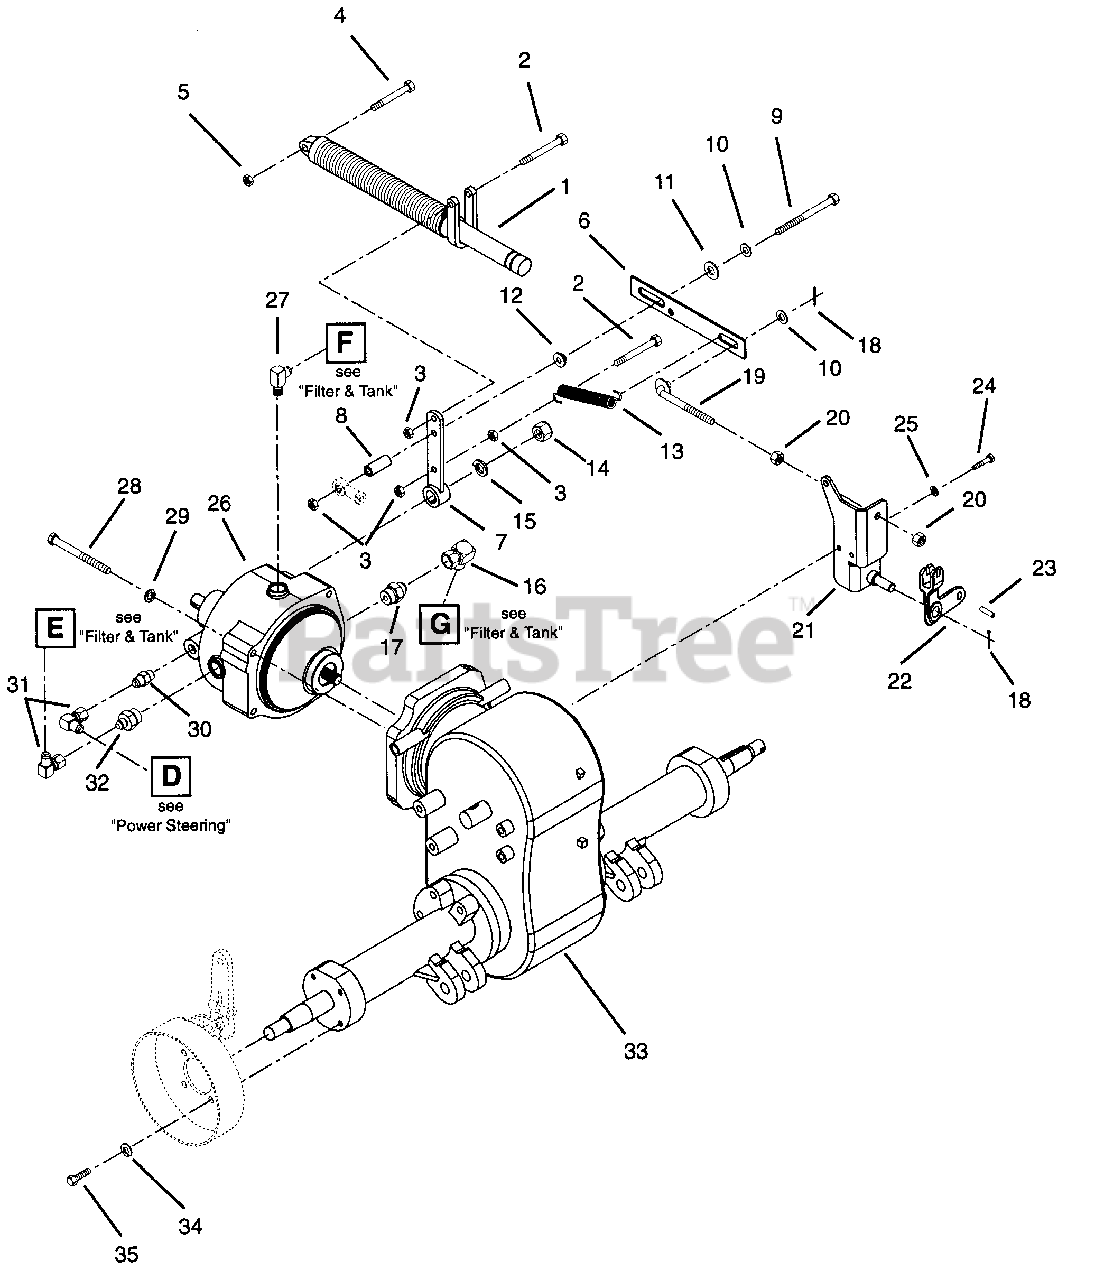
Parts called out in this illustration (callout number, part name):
1	Damper
2	Bolt-Hex .31 - 18 x 2.00 Grade 5
3	Nut-Locking-Nylon .312-18 Grade 2
4	Bolt-Hex .31 - 18 x 1.75 Grade 5
5	Nut-Hex .312-18 Grade 2
6	Strap, Neutral Detent
7	Weldment, Transmission Control Lever
9	Bolt-Hex .31-18 x 3.00 Grade 2
10	Washer-Flat-Steel .406 x 812x .065
11	Washer-Flat-Steel .531 x 1.062 x .095
12	Bushing-Glange .312 x .500 x .344 x .880
13	Spring-tension .091x .500x x 5.50
14	Nut-Locking .50-13
15	Washer-Lock .50
16	Face Seal Adapater
17	Adapter Hydraulic
18	Pin-Cotter .09x .75
19	Weldment, Detent Rod
20	Nut-Hex .375-24 Grade 2
21	Bracket, Hi-Lo Pivot
22	Lever, Hi-Lo
23	Pin-Roll .250 x 1.000
24	Bolt-Hex .25-20 x .75 Grade 5
25	Washer-Lock .250
26	Transmission,Eaton Model 11/1100-061
27	Adapter
28	Bolt-Hex .38-16 x 3.00
29	Washer-Lock .375 x .094
30	Adapter-Pipe
31	Adapter
32	Adapter, Hydraulic
33	Transaxle, Peerless
34	Washer-Lock .313 x .078
35	Bolt-Hex .31-18 x .75 Grade 5
